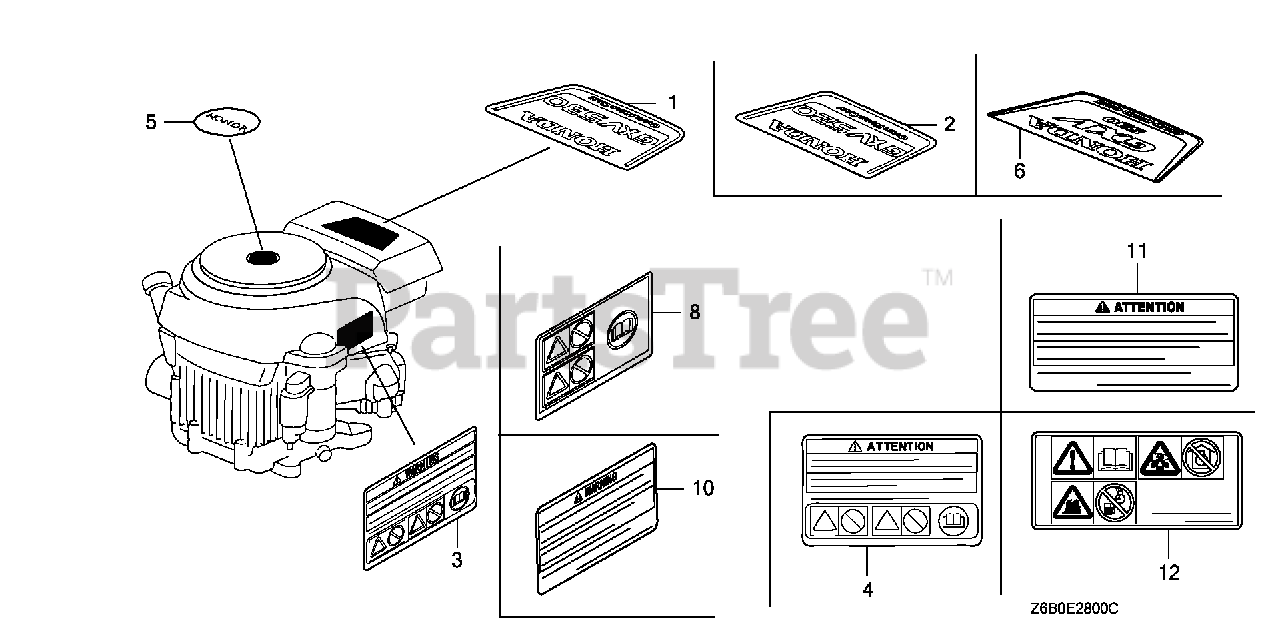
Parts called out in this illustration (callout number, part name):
1	MARK, EMBLEM (GXV530)
3	MARK, OPERATOR CAUTION (ENGLISH)(MADE IN JAPAN)
4	MARK, OPERATOR CAUTION (FRENCH)(MADE IN JAPAN)
6	MARK, EMBLEM (GXV530)
8	MARK, OPERATOR CAUTION (PICTOGRAPH)(MADE IN JAPAN)
10	MARK, OPERATOR CAUTION (ENGLISH)(MADE IN JAPAN)
11	MARK, OPERATOR CAUTION (FRENCH)(MADE IN JAPAN)
12	MARK, OPERATOR CAUTION (PICTOGRAPH)
